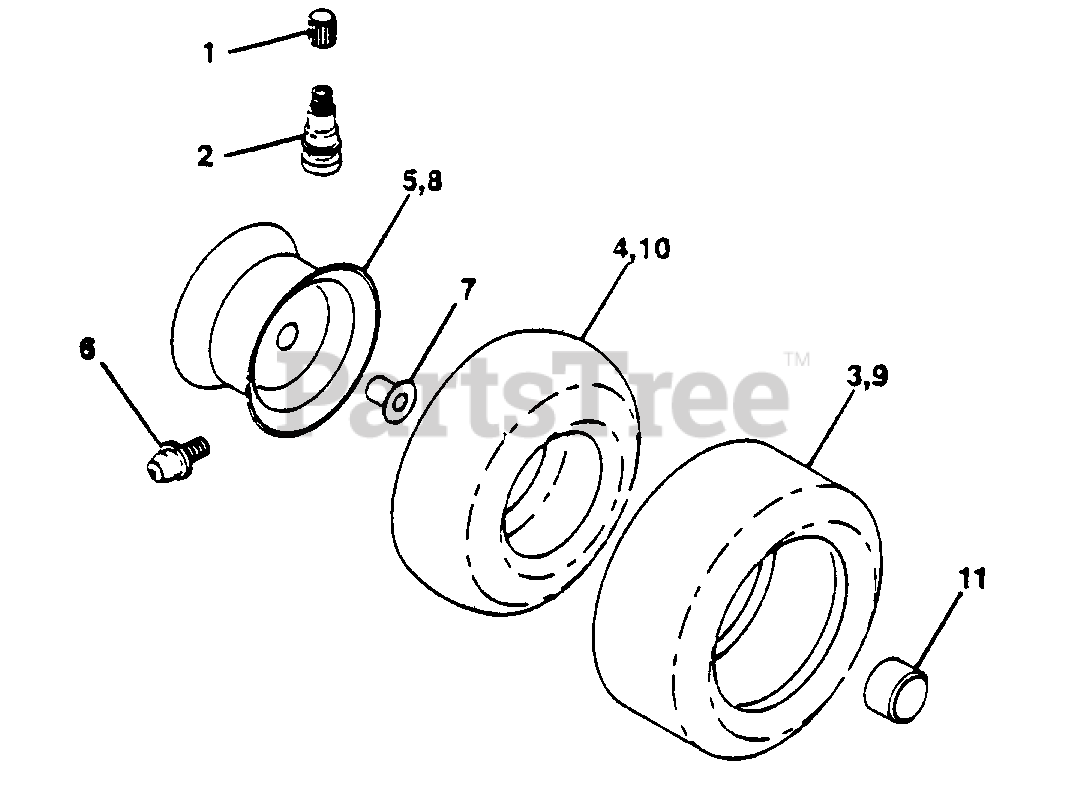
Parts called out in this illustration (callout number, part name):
1	Cap Valve Tire (AYP part number)
2	Stem Valve (AYP part number)
3	Tire F Ts 15 X 60 - 6 Service (AYP part number)
4	Tube Front (Service Item Only)
5	Rim Asm 8"rear Silver Service (AYP part number)
6	Fitting Grease (Front Wheel Only) (AYP part number)
7	Bearing Flange (Front Wheel Only) (AYP part number)
8	Rim Asm 6" front Silver Service (AYP part number)
9	Tire R Ts 20 10 C Service (AYP part number)
10	Tube Rear (Service Item Only) (AYP part number)
11	Cap Hub Axle (AYP part number)
